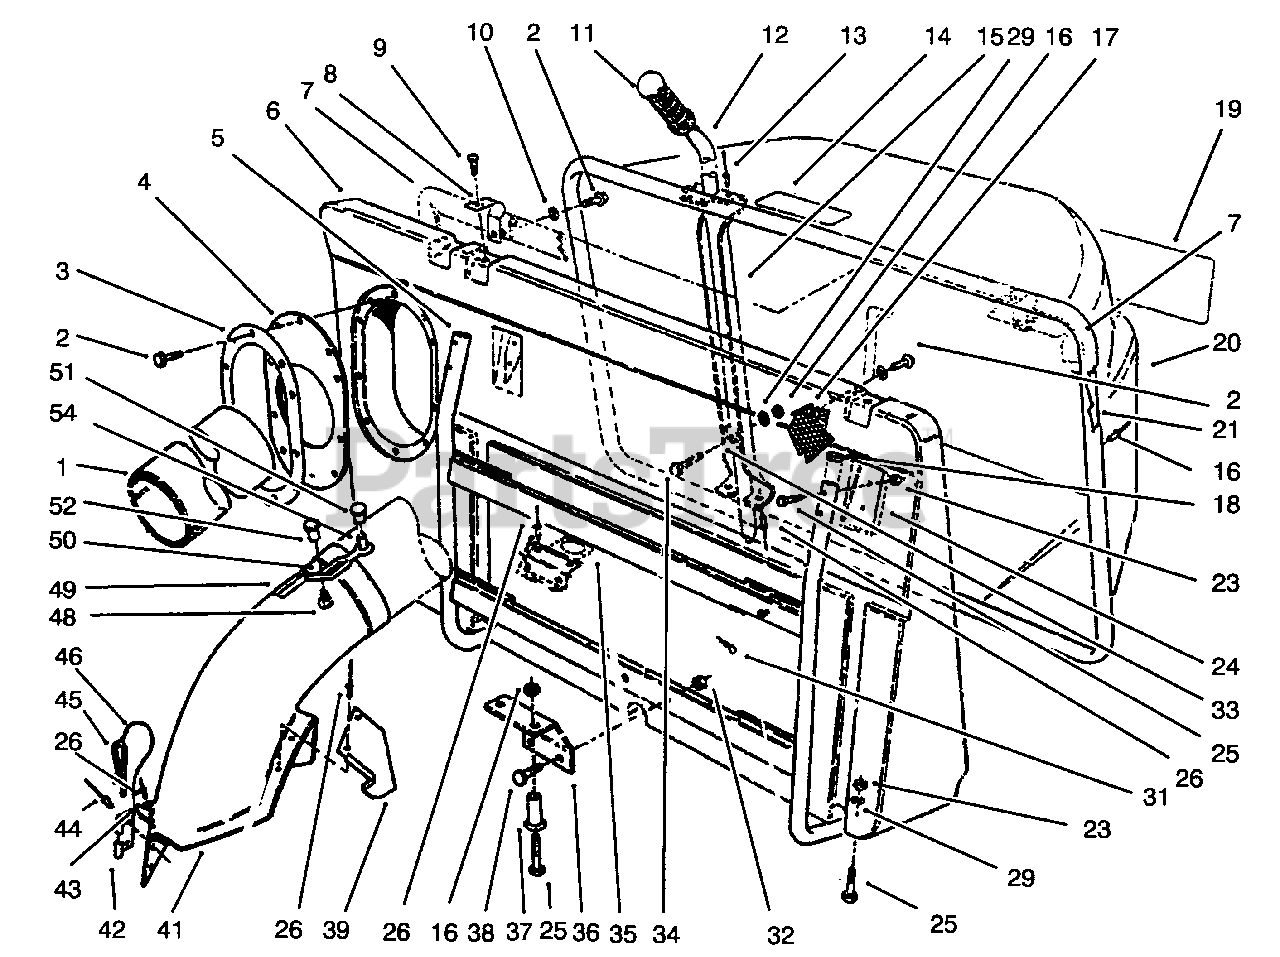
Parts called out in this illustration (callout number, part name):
2	Screw-Self Tapping
3	Ring-Retaining
5	Frame
6	Bag-Front
8	Bracket-Hinge
9	Screw-Button Head
10	Washer-Flat
11	Grip-Handle
12	Handle-Dump
13	Rivet-Pop
14	Decal-Warning
15	Channel-Dump Handle
16	Nut-Lock
17	Screen Bag
19	Decal-Easy-Empty
20	Basket-Grass
21	Frame-Grass Basket
23	Nut-Lock
24	Plate-Backup
26	Rivet-Pop
29	Washer-Flat
31	Pin-Cotter
32	Nut-Lock
33	Guide-Dump Handle
35	Latch
36	Bracket-Latch
37	Spacer
39	Bracket-Chute Support
41	Chute Ass'y. (Incl. Ref.#26, 39, 42-46, 48, 49, & 52)
42	Bracket-Chute Mounting
44	Rivet-Pop
45	Pin-Chute
49	Decal-Danger
50	Retainer-Duct
54	Fastener-Panel
